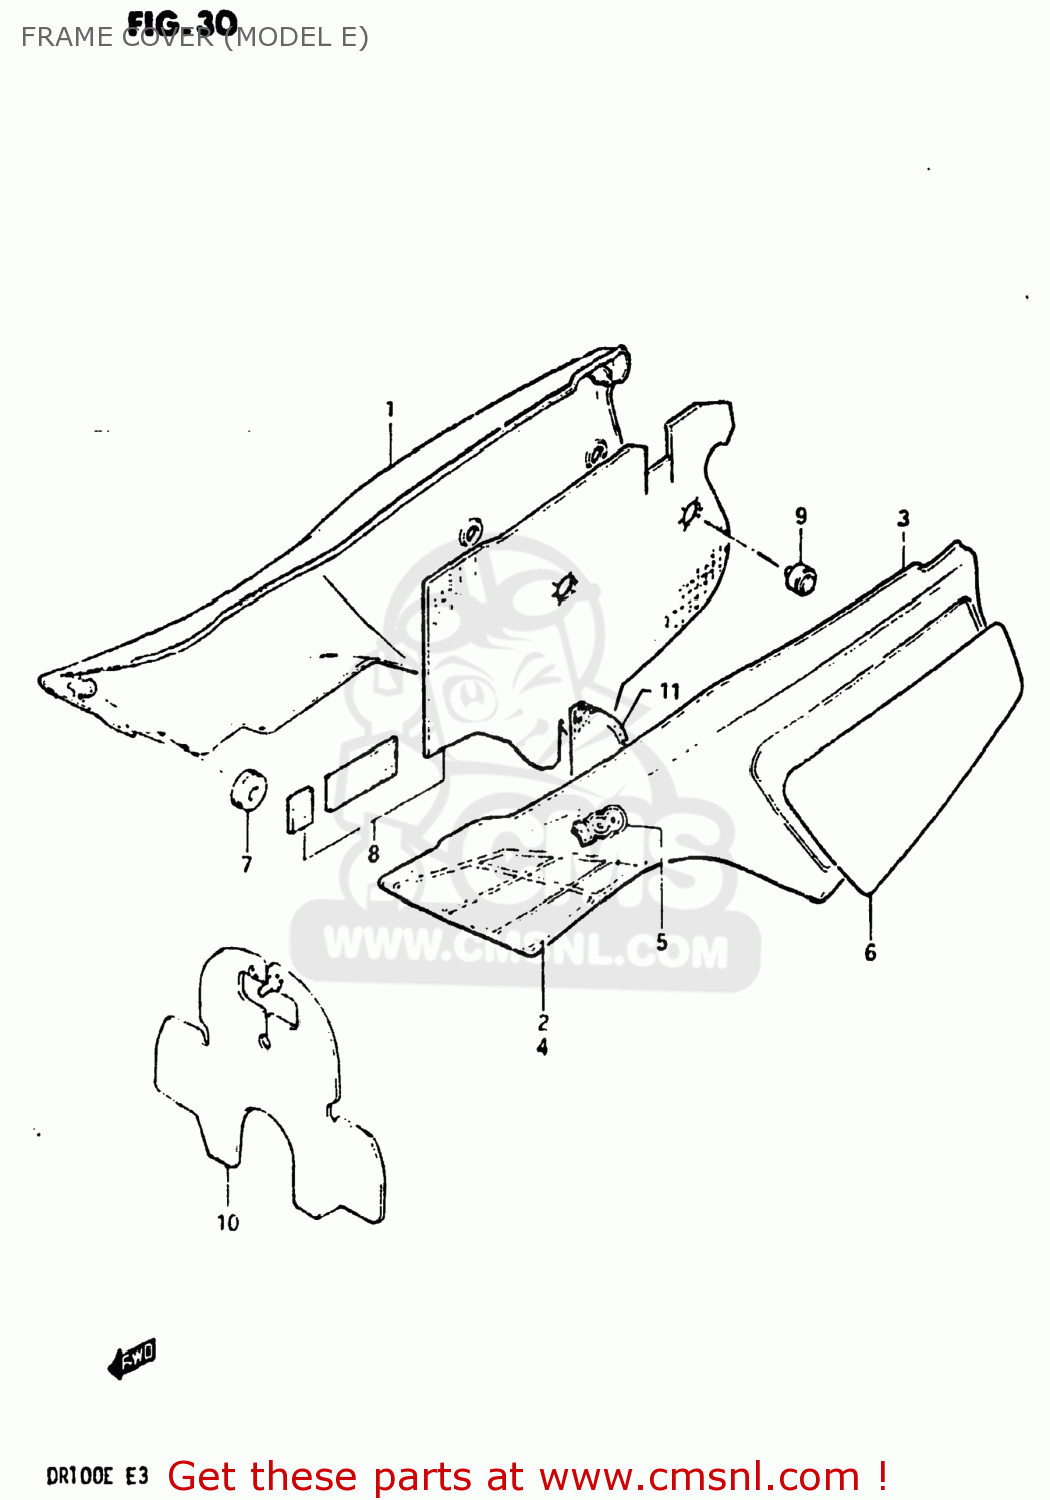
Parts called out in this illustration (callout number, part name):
1	COVER,FRAME,RIGHT
2	TAPE SET,FRAME COVER,RIGHT
3	COVER,FRAME,LEFT
4	TAPE SET,FRAME COVER,LEFT
5	EMBLEM
6	EMBLEM,FRAME COVER,LEFT
7	CUSHION
8	SHIELD SET,FRAME COVER H
9	CUSHION
10	MUD FLAP,FRONT
11	MUD GUARD
